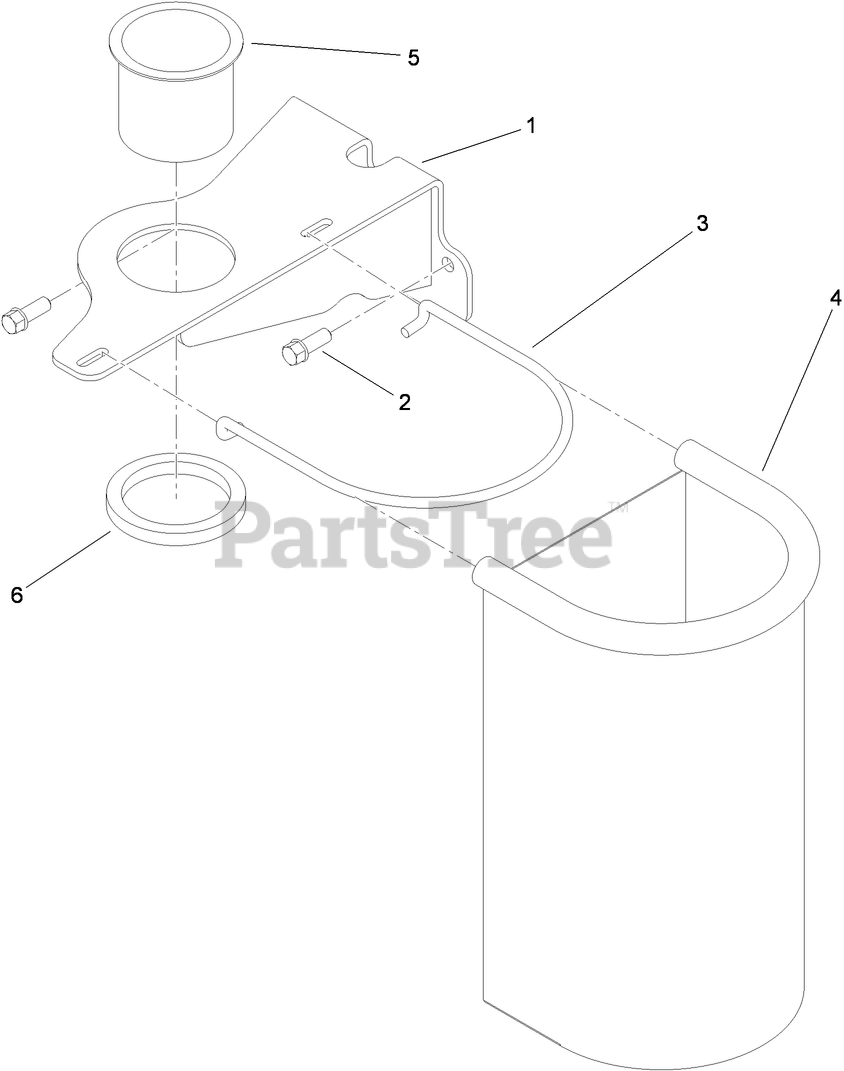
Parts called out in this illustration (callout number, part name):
1	ADAPTER-BAG
2	SCREW-HWH
3	ROD-BAG, TRASH
4	BAG-TRASH
5	HOLDER-CAN, BEVERAGE
6	RING-RUBBER
